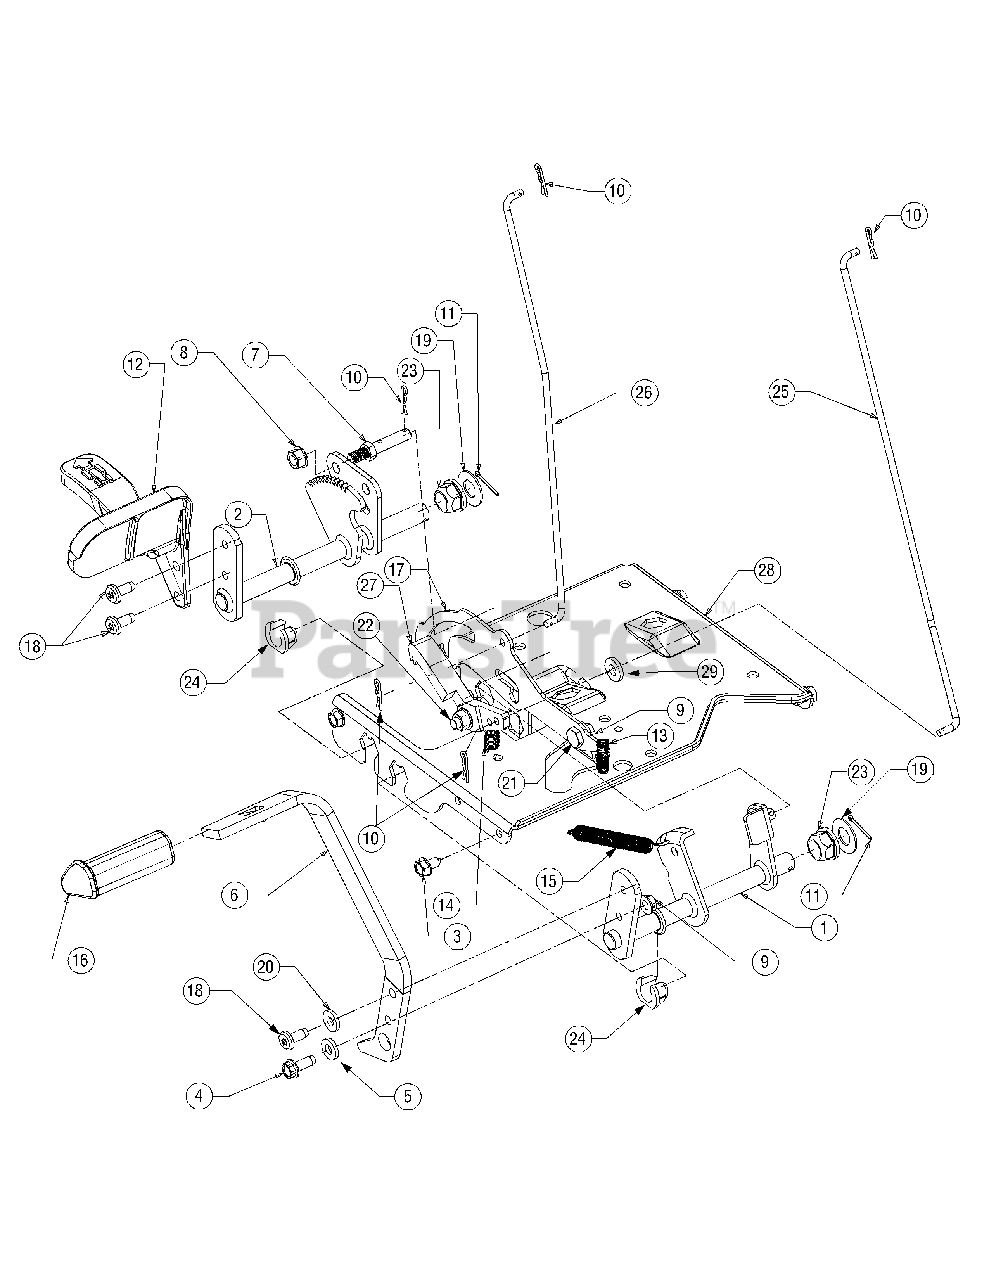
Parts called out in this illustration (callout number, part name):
4	Screw, Self-tapping, 5/16-18, 0.875
5	Washer, Lock, 5/16
8	Nut, Nylon Lock, 3/8-16
9	HEX FLANGE NUT
10	Pin, Cotter, .072 Dia. x 1.13 Lg
11	Pin, Cotter, 3/32, 1.0
12	Pedal, Hydro Control
13	Spring, Compression, .405 x 1.17
14	Spring, Extension, .50 OD x 1.41 Lg
15	Spring, Extension, .50 Dia x 6.37 Lg
16	Pad, Brake, Control
17	Bracket, Lockout, Hydro
18	Screw, Torx Hd. Tapp. 5/16-18 x .75
19	Washer, Flat .64 ID x 1.24 x .06
20	Washer, Flat, .344 x .750 x .120
21	Shoulder, Screw .437
22	Shoulder, Screw 3/8-16
23	Bearing, Hex Flange
24	Bearing, Hex Flange, .628 ID, Split
25	Rod, Control, Cruise
26	Rod, Control, Brake Lock
27	Latch, Cruise
29	Lock Washer,.406 x.875 x.059
